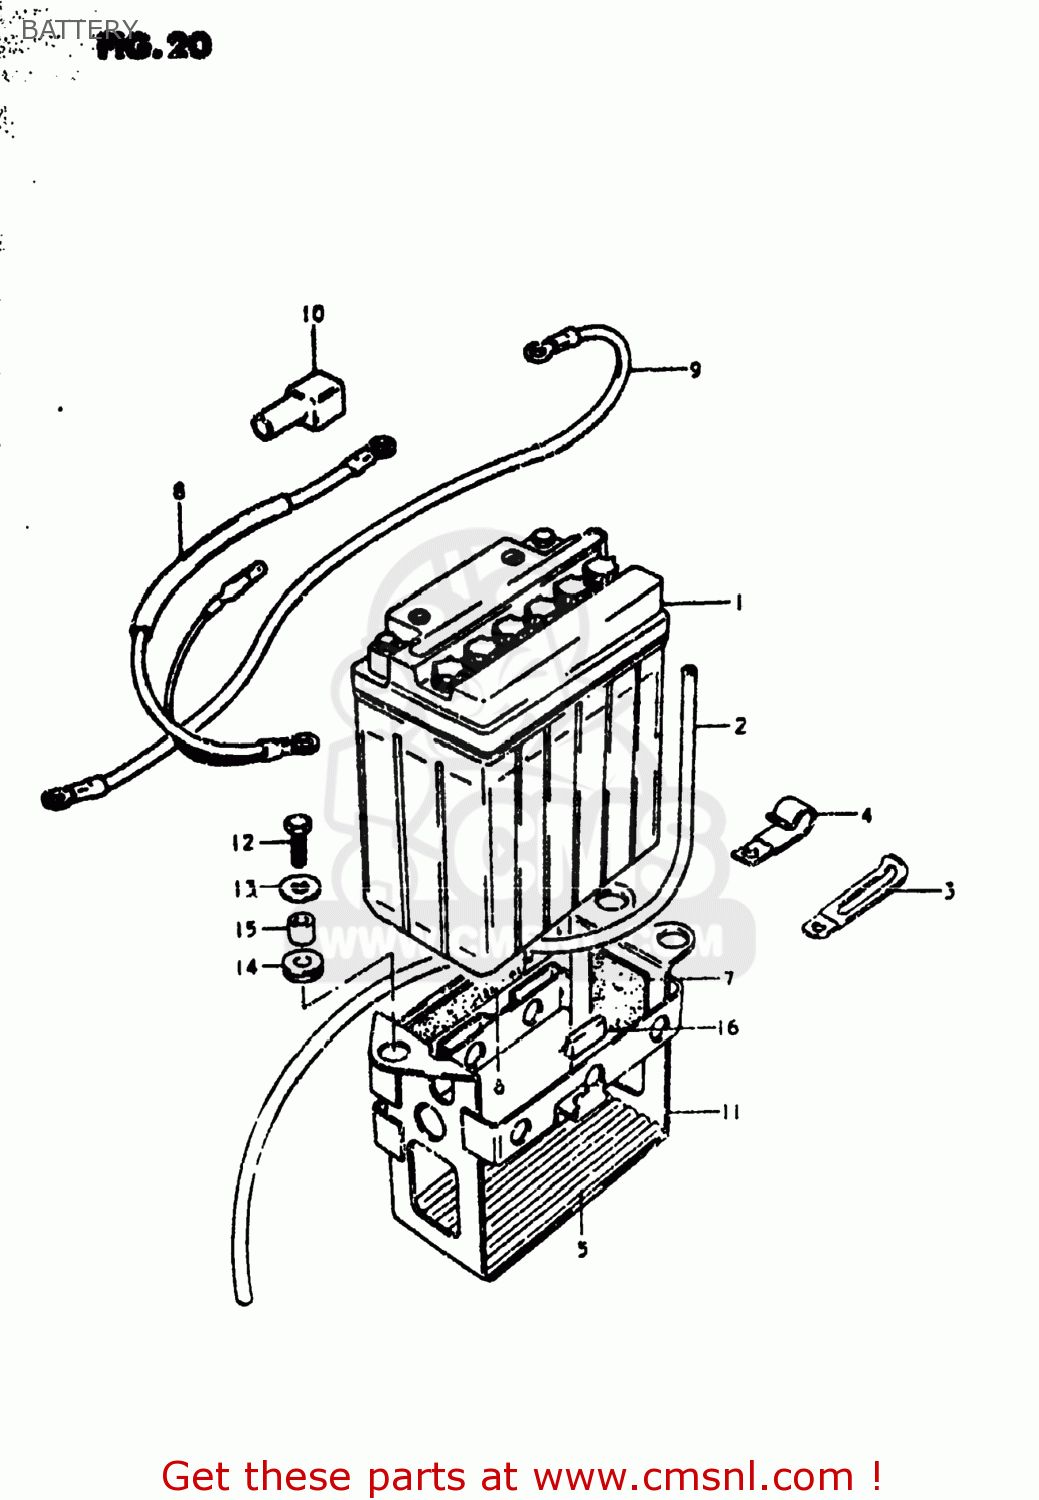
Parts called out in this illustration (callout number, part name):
1	BATTERY ASSY (12V)
2	HOSE,BATTERY EXHAUST
3	CLAMP L:35
4	CLAMP
5	PROTECTOR,BATTERY
6	PROTECTOR(20X90)X4
7	PROTECTOR,BATTERY
8	WIRE,BATTERY PLUS
9	LEAD WIRE,BATTERY(-)
10	CAP,TERMINAL
11	HOLDER,BATTERY
12	BOLT, UPPER
13	WASHER
14	CUSHION
15	SPACER(6.1X9X7.5)
16	CUSHION,FRAME COVER
